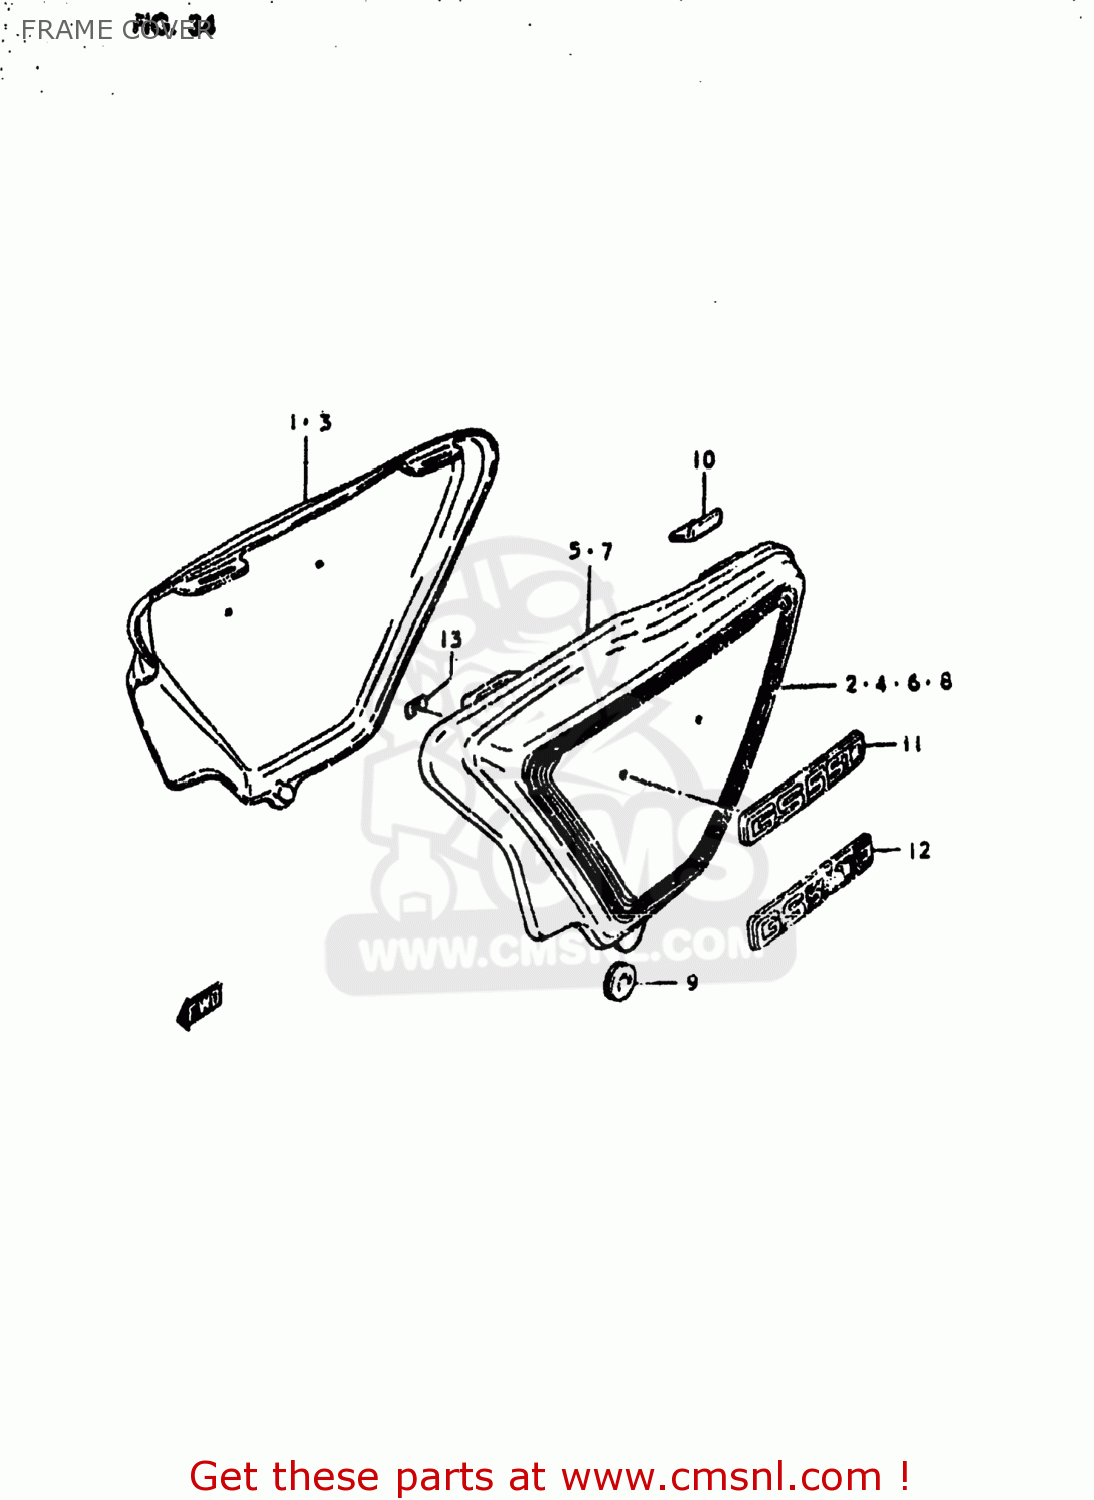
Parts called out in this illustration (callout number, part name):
1	COVER,FRAME,RIGHT
2	TAPE SET,FRAME COVER
3	COVER,FRAME,RIGHT
4	TAPE SET,FRAME COVER
5	COVER,FRAME,LEFT
6	TAPE SET,FRAME COVER
7	COVER,FRAME,LEFT
8	TAPE SET,FRAME COVER
9	CUSHION
10	CUSHION,FRAME COVER
11	EMBLEM,FRAME COVER
12	EMBLEM,FRAME COVER
13	NUT
